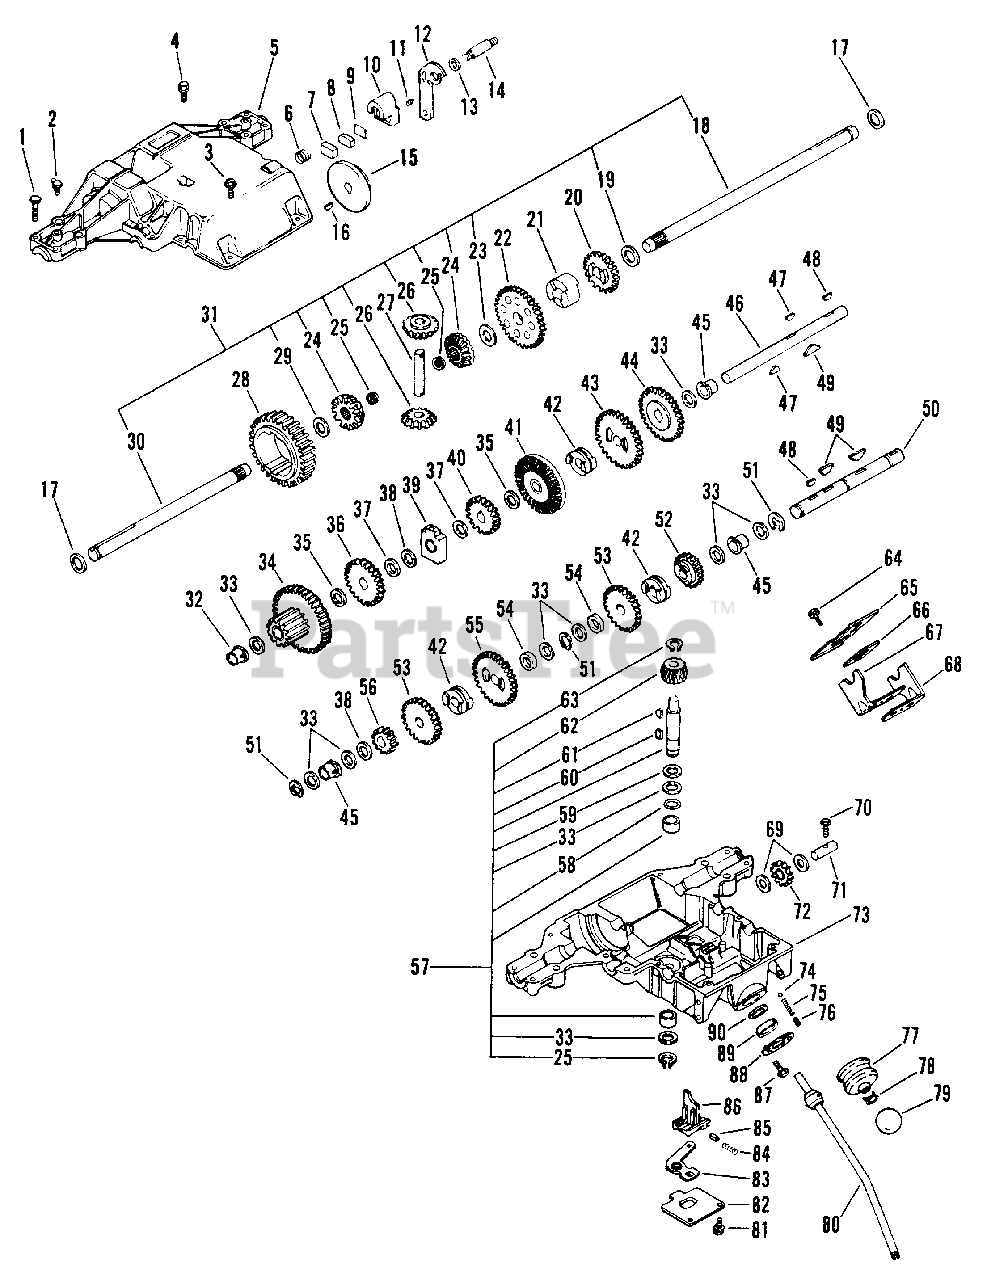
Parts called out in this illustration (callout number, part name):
1	BOLT, HEX 1/4-20X1.25
2	FITTING, ZERK
3	BOLT, HEX 1/4-20X.875
4	SCREW, MACHINE #12-24X.625
5	ASSEMBLY, LOWER HOUSING
6	SPRING, COMPRESSION
7	PUCK, FRICTION
8	PUCK, FRICTION(INNER)
9	SPACER
10	ASSEMBLY, BRAKE JAW
11	SETSCREW, NO.8-32
12	LEVER, ACTUATING ASSEMBLY
13	WASHER
14	BOLT, SHOULDER
15	DISC, BRAKE
16	KEY, WOODRUFF .187X.625 HRD #61
17	SEAL, FELT
18	AXLE, R.H.
19	WASHER, FLAT .813X1.37X.100
20	GEAR, SPUR 22T
21	LOCK, GEAR
22	GEAR, SPUR 35T
23	WASHER, .031
24	GEAR, 15 TOOTH W/SPLINE
25	RING, RETAINING
26	GEAR, 15 TOOTH W/O SPLINE
27	SHAFT, CROSS
28	GEAR, SPUR 32T
29	KIT, SHIM
30	AXLE, L.H.
31	KIT, TRANSMISSION REPAIR
32	BEARING, FLANGE
33	PACKAGE, SHIM
34	ASSEMBLY, GEAR 12T
35	WASHER
36	GEAR, SPUR 25T
37	WASHER, .025
38	SPACER
39	ASSEMBLY, SHAFT SUPPORT
40	GEAR, SPUR 20T
41	ASSEMBLY, BEVEL GEAR
42	COLLAR, CLUTCH
43	GEAR, SPUR 33T
44	GEAR, SPUR 30T
45	BUSHING, FLANGE
46	SHAFT, DRIVE
47	KEY, WOODRUFF
48	KEY, WOODRUFF .125X.50 HRD #3
49	KEY, HI-PRO
50	SHAFT, INTERMEDIATE
51	RING, SNAP
52	GEAR, SPUR 20T
53	GEAR, SPUR 25T
54	SPACER
55	GEAR, SPUR 30T
56	GEAR, SPUR 13T
57	ASSEMBLY, INPUT SHAFT
58	"O" RING
59	WASHER
60	KEY, WOODRUFF 3/16X3/4 #9
61	KEY, WOODRUFF .125X.50 HRD #3
62	ASSEMBLY, PINION AND SHAFT
63	RING, SNAP EXTERNAL
64	BOLT, HEX 1/4-28X.75
65	PLATE, LOCKOUT
66	PLATE, FORK SUPPORT
67	FORK, SHIFTER
68	FORK, SHIFTER
69	WASHER, .020 THICK
70	SCREW, MACHINE #10-24X1.00
71	SHAFT, IDLER
72	ASSEMBLY, IDLER GEAR
73	HOUSING, UPPER
74	BALL, DETENT
75	SPRING, DETENT
76	SCREW, SET 1/4-20X.375 H/SCK
77	BOOT, TRANSMISSION
78	CLAMP, HOSE
79	KNOB, ADJUSTMENT CONTROL
80	ASSEMBLY, SHIFT LEVER
81	SCREW, MACHINE 8-32X.50
82	PLATE, HI-LO COVER
83	LEVER, HI-LO SHIFT
84	SPRING, DETENT
85	PIN, DETENT
86	FORK, HI-LO SHIFTER
87	SCREW, MACHINE 10-24X.50
88	COVER
89	INSERT, NYLON
90	WASHER, WAVE
